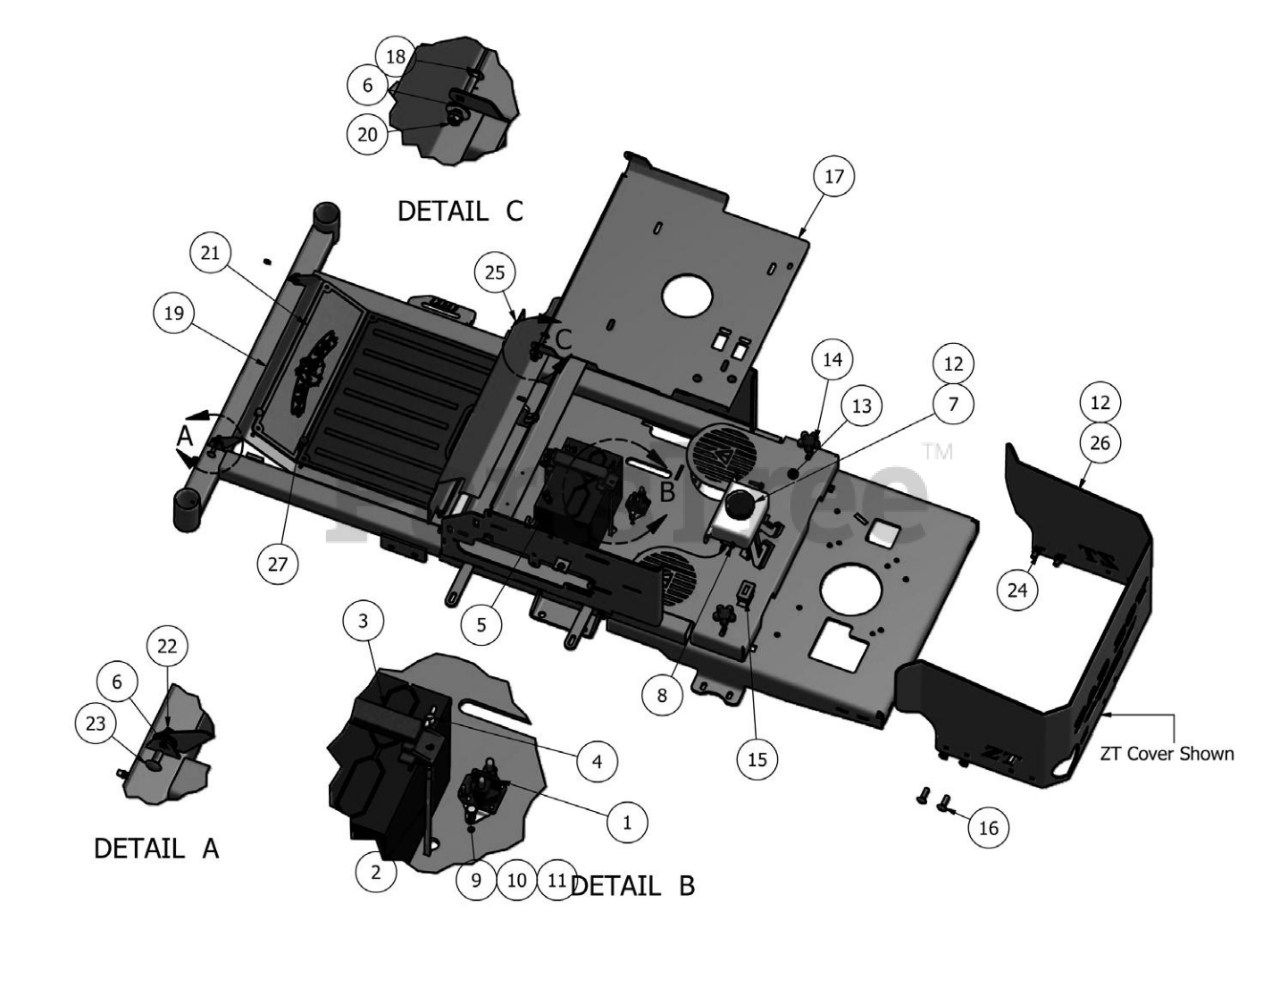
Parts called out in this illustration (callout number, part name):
2	7" Stove Bolt
3	Battery Holder
4	1/4" Wing Nut
5	Battery (Workaholic)
6	7/16" X 2" Washer
7	Hydraulic Tank& Cap
8	Hydro Tank Cap
9	1/4-20 x 3/4 GR 5 Hex Bolts Zinc
10	1/4" Lock Washer
11	1/4" Hex Nut
12	Rear Cover 23hp
14	5/16" Knob
15	Tachometer
16	3/8" x 1 1/4" Carriage Bolt
17	Seat Plate
18	5/16" x 1 1/4" Carriage Bolt
19	Floor Panel
20	5/16" Nylock Flange Nut
21	Floorboard Mat
22	1/4" Nylock Nut
23	Round Head Short Square Neck Bolt
24	3/8" Flange Nut
25	Cooler Cover
26	Rear plate 26hp
27	Ratchet Fastener
